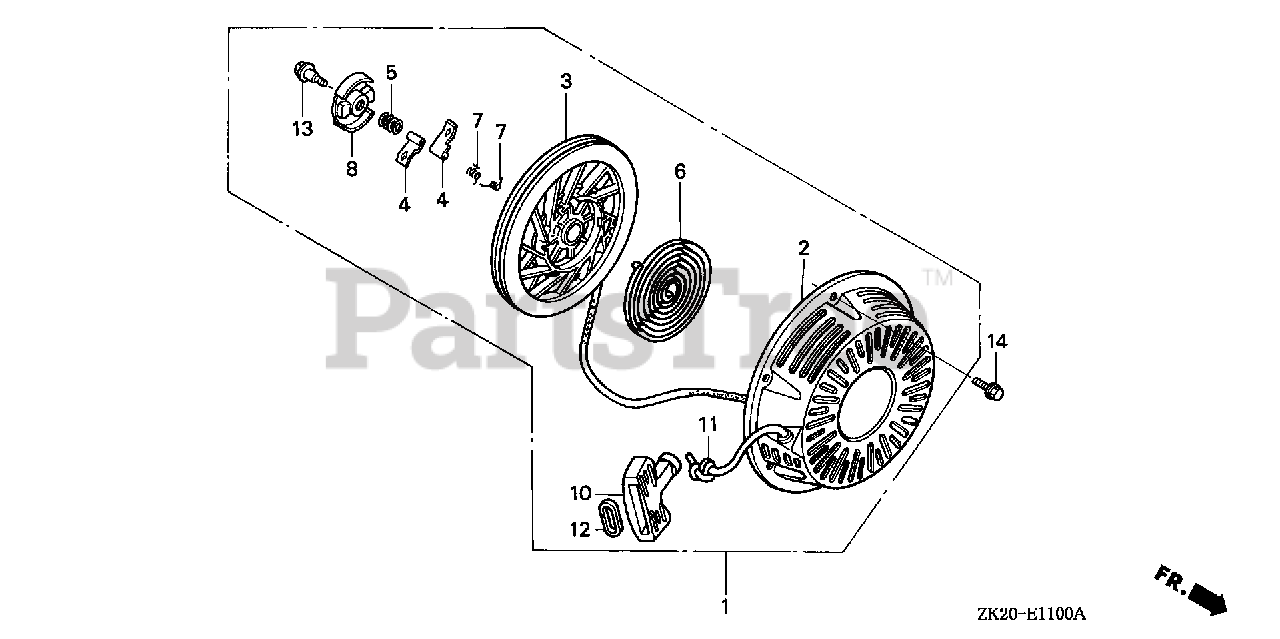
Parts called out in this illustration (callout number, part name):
1	STARTER ASSY., RECOIL *R280* (POWER RED)
1	STARTER ASSY., RECOIL *NH1* (BLACK)
1	STARTER ASSY., RECOIL *T68* (TSURUMI BLUE)
1	STARTER ASSY., RECOIL *Y131* (LIGHTNING YELLOW)
1	STARTER ASSY., RECOIL *T80* (BAKERITE ORANGE)
2	CASE, RECOIL STARTER *R8* (BRIGHT RED)
2	CASE, RECOIL STARTER *NH1* (BLACK)
2	CASE, RECOIL STARTER *T68* (TSURUMI BLUE)
2	CASE, RECOIL STARTER *Y131* (LIGHTNING YELLOW)
2	CASE, RECOIL STARTER *T80* (BAKERITE ORANGE)
2	CASE, RECOIL STARTER *R280* (POWER RED)
3	PULLEY, RECOIL STARTER
4	RATCHET, STARTER
5	SPRING, FRICTION
6	SPRING, STARTER RETURN
7	SPRING, RATCHET
8	RETAINER, SPRING
10	GRIP, STARTER
11	ROPE, RECOIL STARTER
13	SCREW, CENTER
14	BOLT, FLANGE (6X10)
